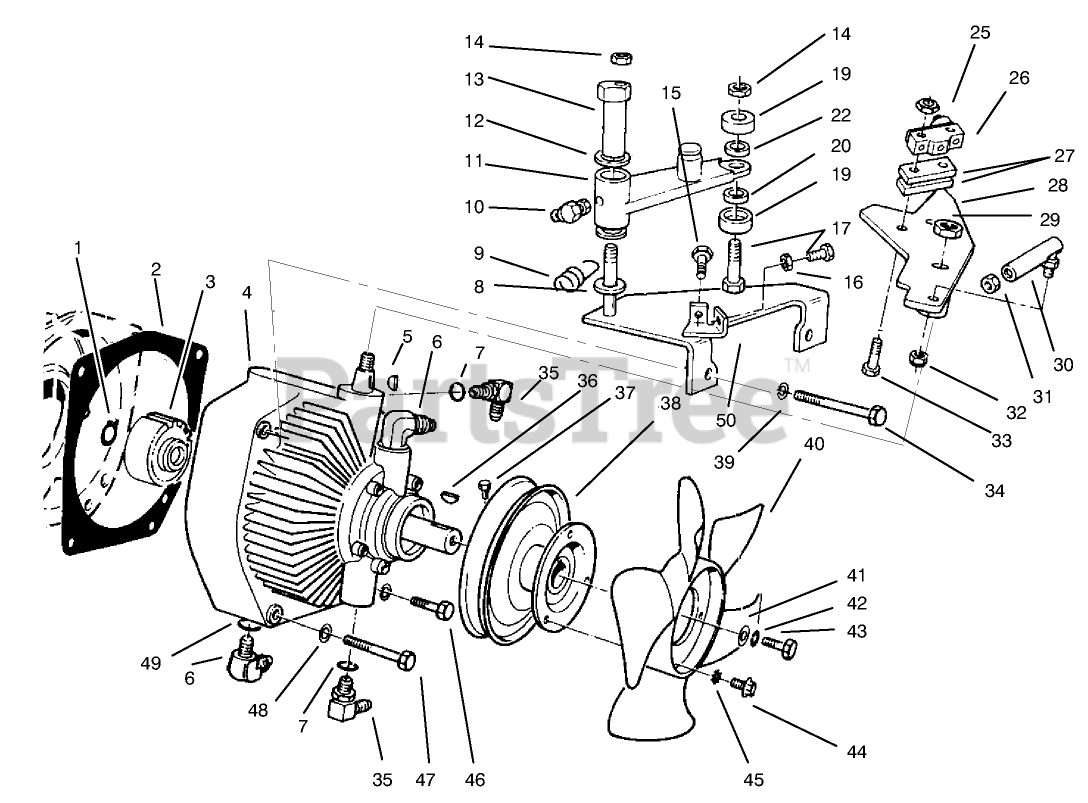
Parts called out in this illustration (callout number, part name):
1	RING-SNAP, EXTERNAL
2	TRANS GASKET
3	GEAR-SPUR
4	HYDROSTATIC TRANS.
5	KEY-WOODRUFF
6	Fitting-Hydraulic 90deg. (Incl. Ref. #49)
7	O-RING
8	WASHER-FLAT
9	SPRING-EXTENSION
10	FITTING-GREASE
11	NEUTRAL SWITCH ARM ASSY
12	WASHER-THRUST
13	STUD-TRACTION
14	NUT-LOCK, NI
15	SCREW-HH
16	NUT-HEX
17	SCREW-HH
19	BEARING-BALL
20	SPACER
22	SPACER-BEARING
25	NUT-HEX
26	SWITCH-MICRO
27	PLATE-SWITCH
28	Lever-Traction
29	NUT-LOCK, NI
30	JOINT-BALL
31	NUT-JAM
32	NUT-LOCK
33	SCREW-PPH
34	SCREW-HH
35	Fitting-Hydraulic 90deg. (Incl. Ref. #7)
36	KEY-WOODRUFF
37	SCREW-SQH
38	TRANS PULLEY
39	WASHER-LOCK
40	FAN 8"
41	WASHER-FLAT
42	WASHER-LOCK
43	SCREW-HH
44	SCREW-SHWH
45	WASHER-LOCK/EXT
46	SCREW-HH
47	SCREW-HH
48	WASHER-LOCK
49	O-RING
50	Plate-Traction
